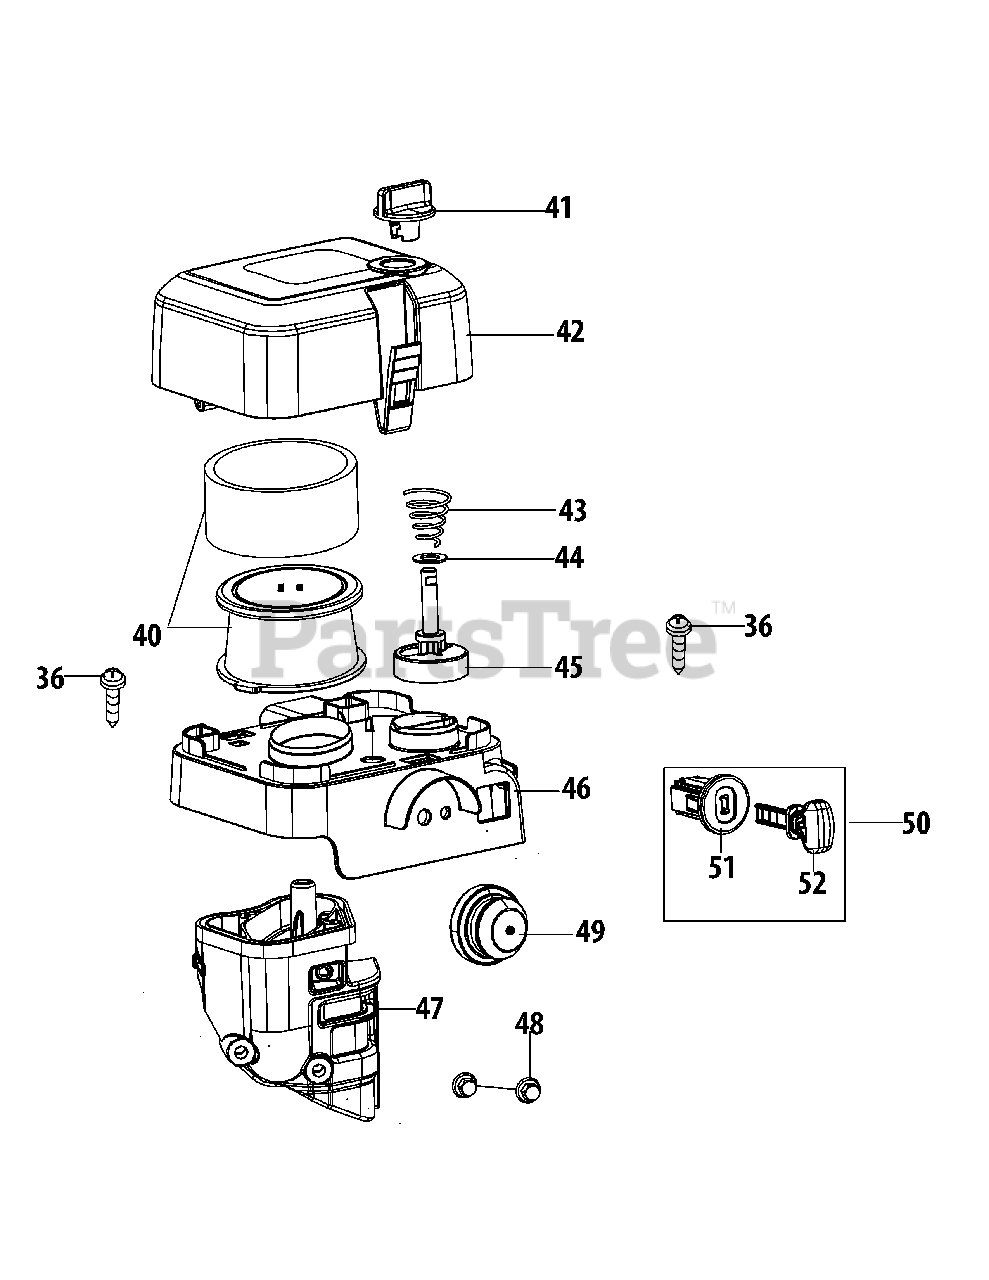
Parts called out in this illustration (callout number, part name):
36	Screw 4.2×20
40	Air Filter Element
41	Knob
42	Air Filter Cover
43	Taper Spring
44	Washer 9×1×16
45	The Air Filter Shaft
46	Silencer Plate
47	Air Filter Base
50	Engine Switch
51	Engine Switch Base
52	Engine Switch Key
